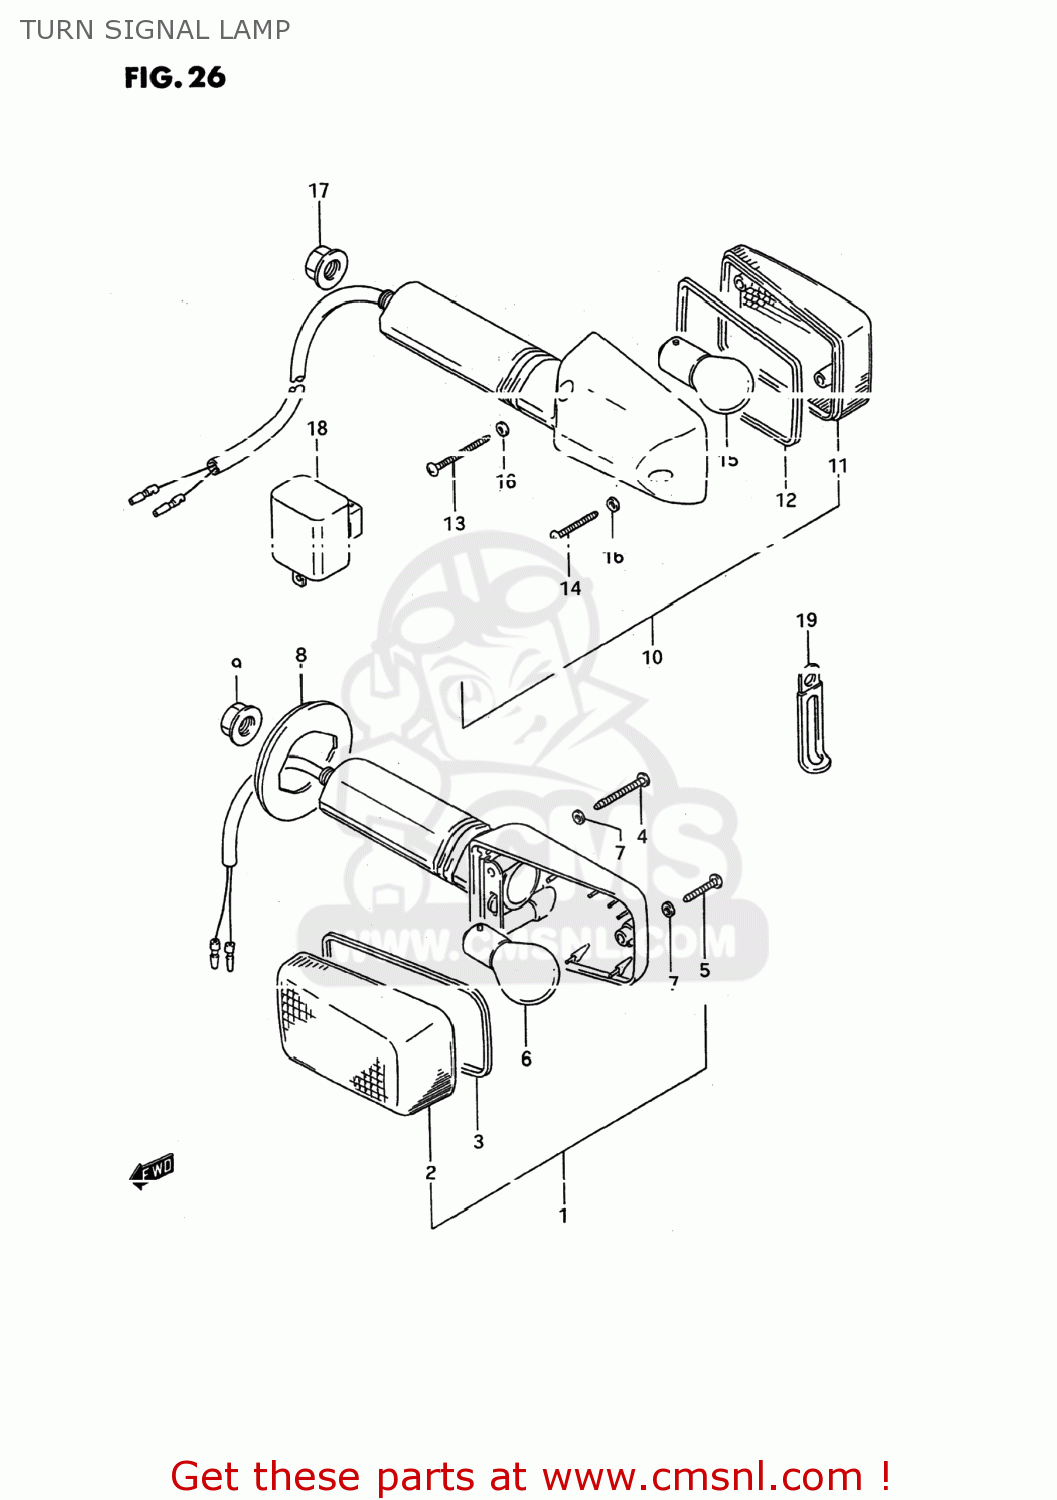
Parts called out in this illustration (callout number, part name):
1	LAMP ASSEMBLY,FRONT TURN SIGNAL
2	LENS
3	GASKET (NAS)
4	SCREW(3X30)
5	SCREW
6	BULB(12V21W)
7	GASKET (NAS)
8	GROMMET
9	NUT
10	LAMP ASSEMBLY,REAR TURN SIGNAL
11	LENS
12	GASKET (NAS)
13	SCREW(3X30)
14	SCREW
15	BULB(12V21W)
16	GASKET (NAS)
17	NUT
18	RELAY,TURN SIGNAL
19	CLAMP(L:45)
